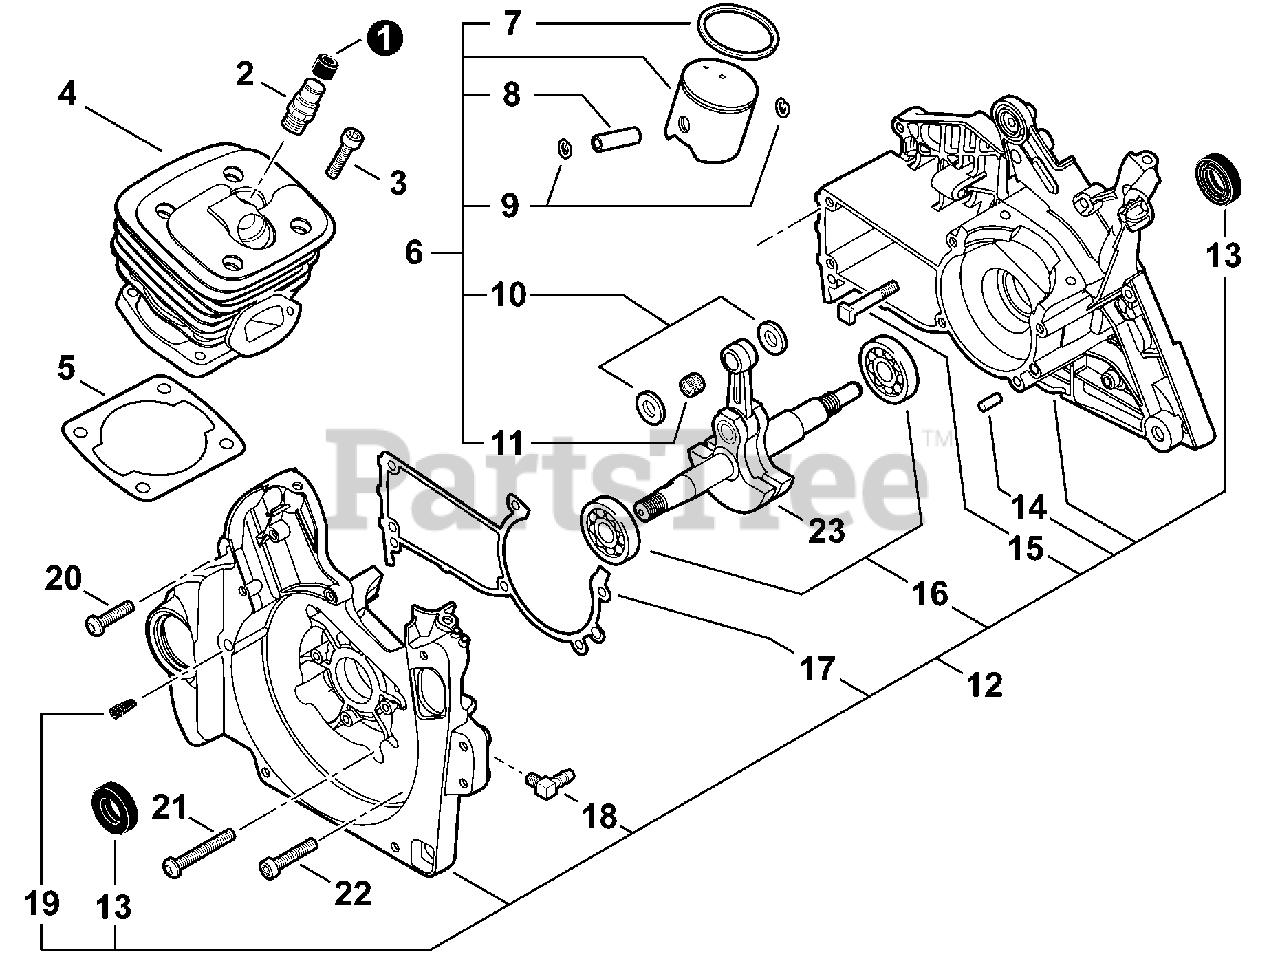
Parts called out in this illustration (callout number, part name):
1	COVER, DUST
2	VALVE ASSY, DECOMPRESSION
3	BOLT, TORX 5×25
4	CYLINDER
5	GASKET, CYLINDER
6	PISTON KIT
7	RING, PISTON
8	PIN, PISTON
9	RING, SNAP Ø11
10	WASHER, THRUST
11	BEARING, NEEDLE 11
12	CRANKCASE SET
13	SEAL, OIL 15
14	PIN, LOCATING 5×10
15	BOLT, STUD M8×1.25×34.5
16	BEARING, BALL 6202
17	GASKET, CRANKCASE
18	CONNECTOR, PIPE
19	VENT ASSY
20	BOLT, TORX 5×20
21	BOLT, TORX 5×35
22	BOLT, TORX 5×25
23	CRANKSHAFT ASSY
